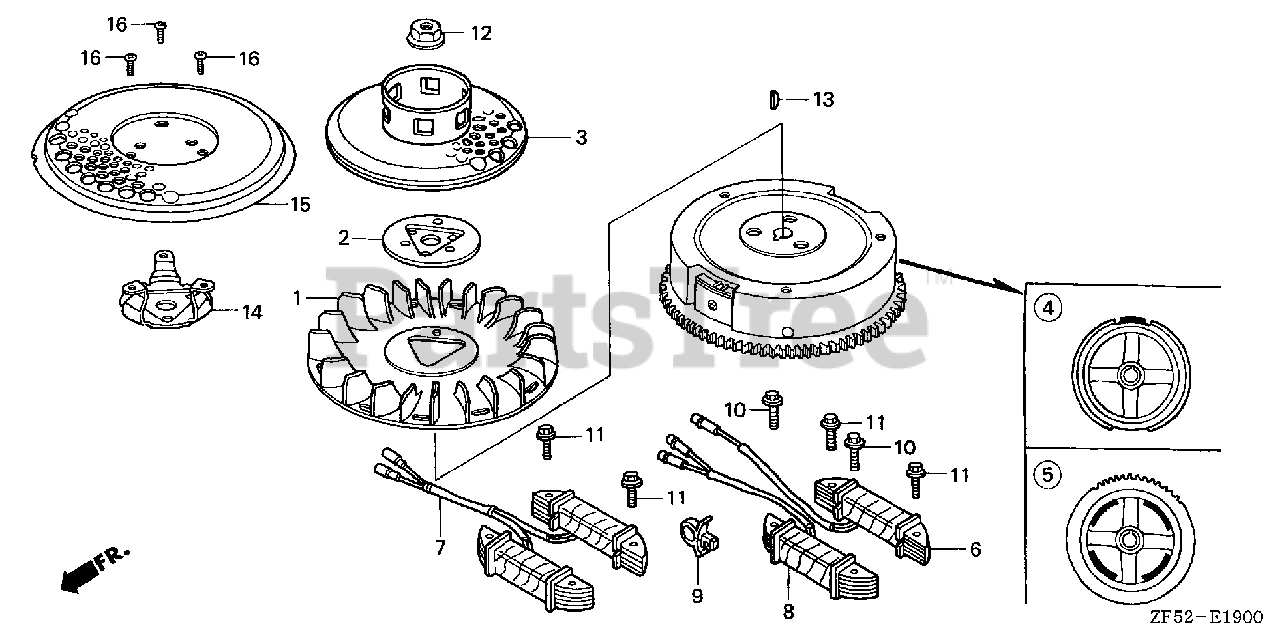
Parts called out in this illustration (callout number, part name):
1	FAN, COOLING
3	PULLEY, STARTER (SCREEN GRID)
9	CLIP, BRAKE PIPE (A)
12	NUT, SPECIAL (16MM)
13	KEY, SPECIAL WOODRUFF (25X18)
